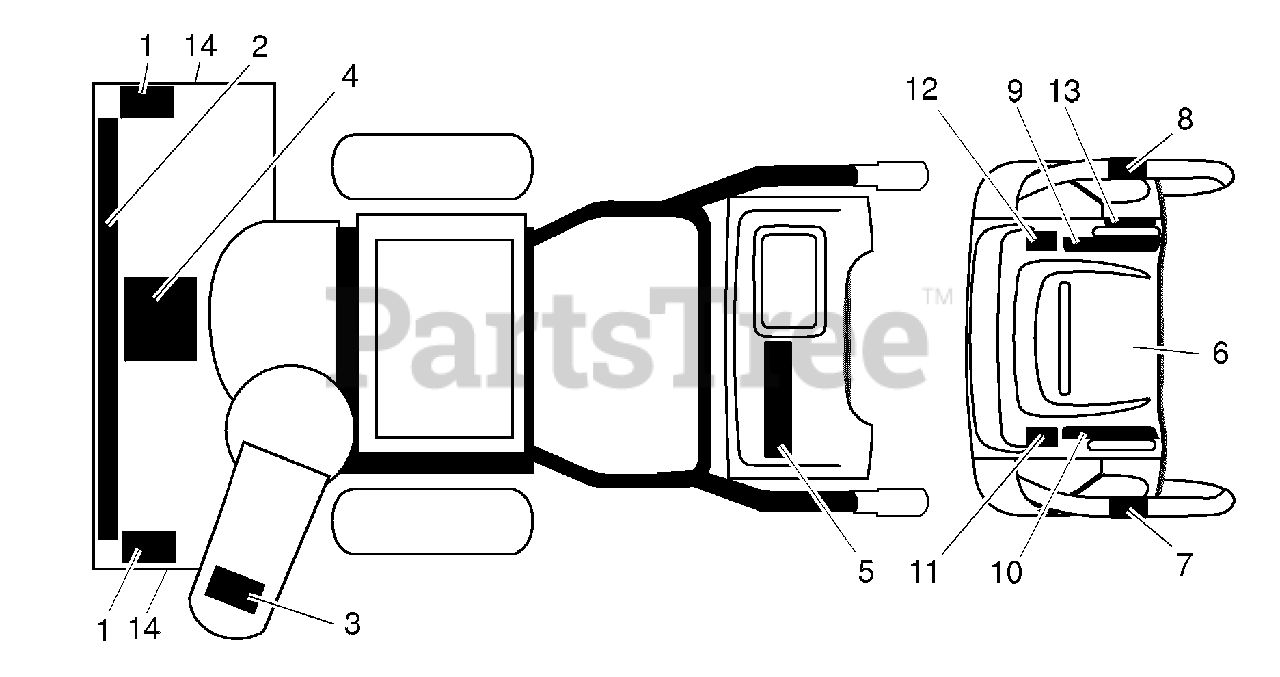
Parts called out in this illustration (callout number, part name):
1	Decal, Danger
2	Decal, Husqvarna
3	Decal, Danger, Defl ector
4	Decal, Danger
5	Decal, Husqvarna, 1330SBE
6	Decal, Instruction
7	Decal, Traction Lever
8	Decal, Auger Lever
9	Decal, Speed Control
10	Decal, Remote Defl ector
11	Decal, LH Trigger
12	Decal, RH Trigger
13	Decal, Console, Hydro
14	Decal, Husqvarna, Crown
